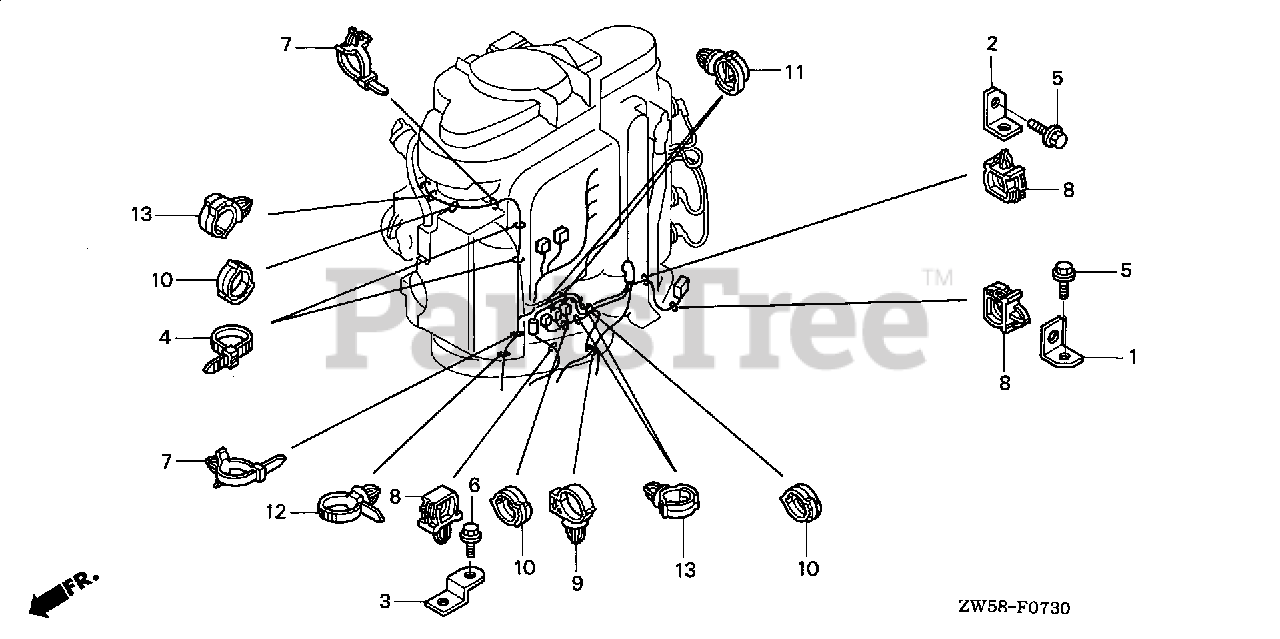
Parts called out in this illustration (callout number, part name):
1	BRACKET, CLIP (C)
2	BRACKET, CLIP (D)
3	BRACKET, CLIP (E)
4	BAND (BLACK 3.5X140)
5	BOLT, FLANGE (6X12) (CT200)
6	BOLT, FLANGE (6X14)
7	BAND, WIRE HARNESS (150MM) (NATURAL)
8	CLIP, WIRE HARNESS (10MM)
9	CLAMP, HARNESS
10	CLIP, WIRE HARNESS
11	CLIP, HARNESS
12	BAND, WIRE HARNESS (123.5MM) (BLUE)
13	CLIP, WIRE HARNESS (BLACK)
